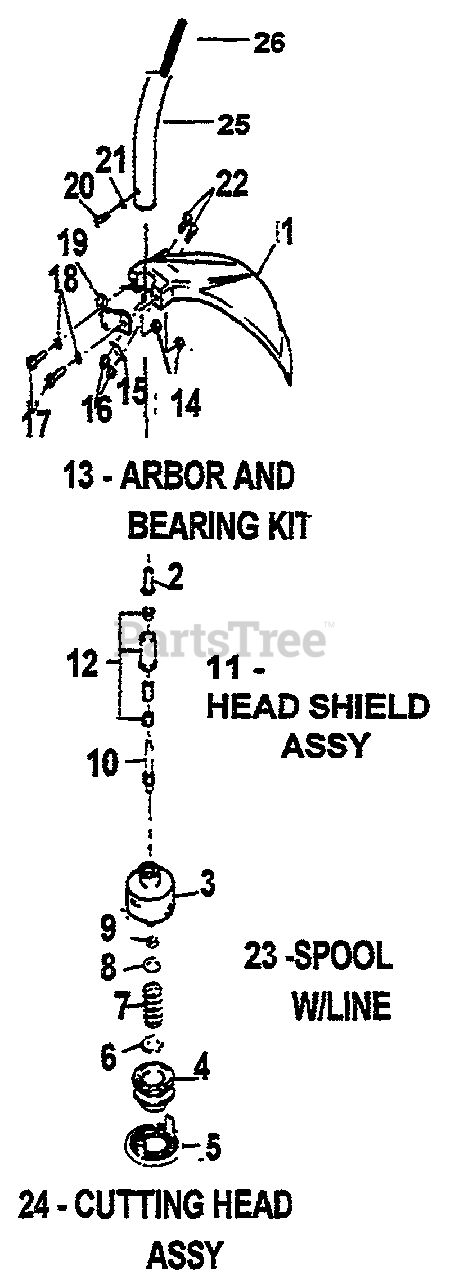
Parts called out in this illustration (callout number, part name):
1	DEFLECTOR
2	ARBOR ADAPTER
3	HEAD BODY
5	CAP
6	SPRING PLATE
7	SPRING
8	SPRING PLATE
10	ARBOR POST
11	HEAD SHIELD) ASSY
12	ARBOR BUSH ASSY
13	ARBOR & BRG KIT
14	NUT
15	BLADE, CUT OFF
19	BRACKET CLAMP
23	SPOOL & LINE
24	HEAD ASSEMBLY
25	TUBE ASSY
26	FLEX CABLE
